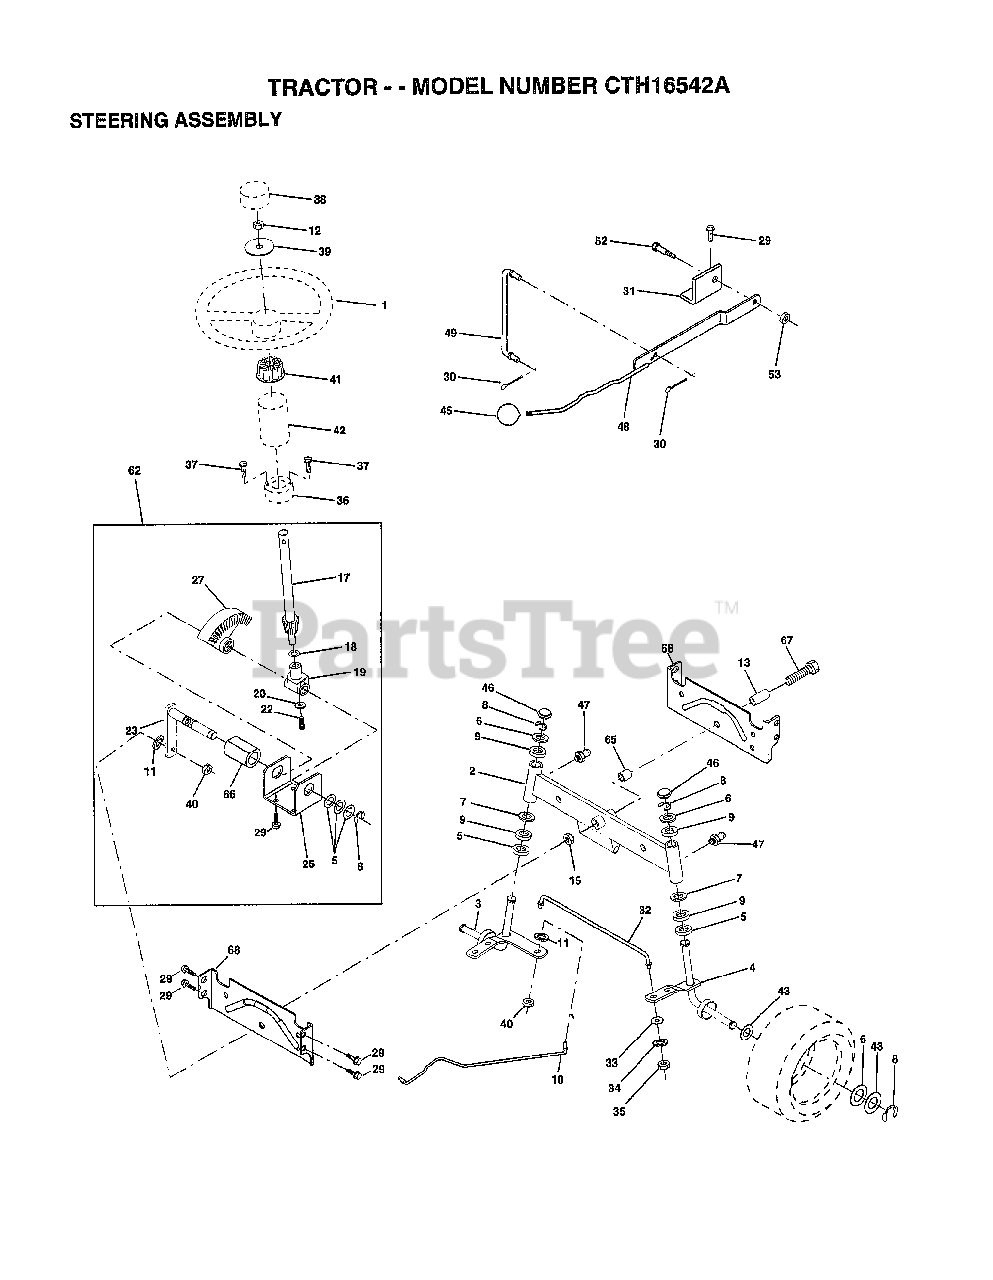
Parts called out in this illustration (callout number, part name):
1	WHEEL STR AYP BLK
2	AXLE ASM
3	SPINDLE.ASM.LH
4	"SPINDLE ASM,RH"
5	WASHER .T
6	WASHER
7	WASHER
8	RING
9	COL. SRTG. BEAR.
10	DRAGLINK-STAMPED
11	LOCKWASHER
13	BEARING AXLE
15	"NUT-LOC,FLANGE LT"
17	SHAFT ASM STEERNG
18	THRUST WASHER
19	SUPPORT.SHAFT
22	SCREW HEX SOC1/4-
25	BRKT-STEERING
27	GEAR SECTOR
29	SCREW
30	COTTER PIN
31	BRKT.PVT.MAN.LVR.
32	ROD.TIE.19.75
33	WASHER M
34	LOCKWASHER
35	NUT.LOCK.5/16-24
36	BUSHING.STRG.3/4
37	"SCREW-TT,10-32 FL"
38	CAP STEER AYP
39	WASHER
40	GRIPCO NUT
41	ADAPTER LT
42	BOOT SHAFT STEER
45	KNOB.RD.7/16-14
46	CAP
47	ZERK M
48	LEVER.ASM.CLUTCH
49	LINK CLTCH W/NUTS
52	"BOLT, SHOULDER LT"
62	KIT STEERING ASM
65	SPACER AXLE
66	"BEARING-ARM,PITMA"
67	BOLT
68	BRACE AXLE
